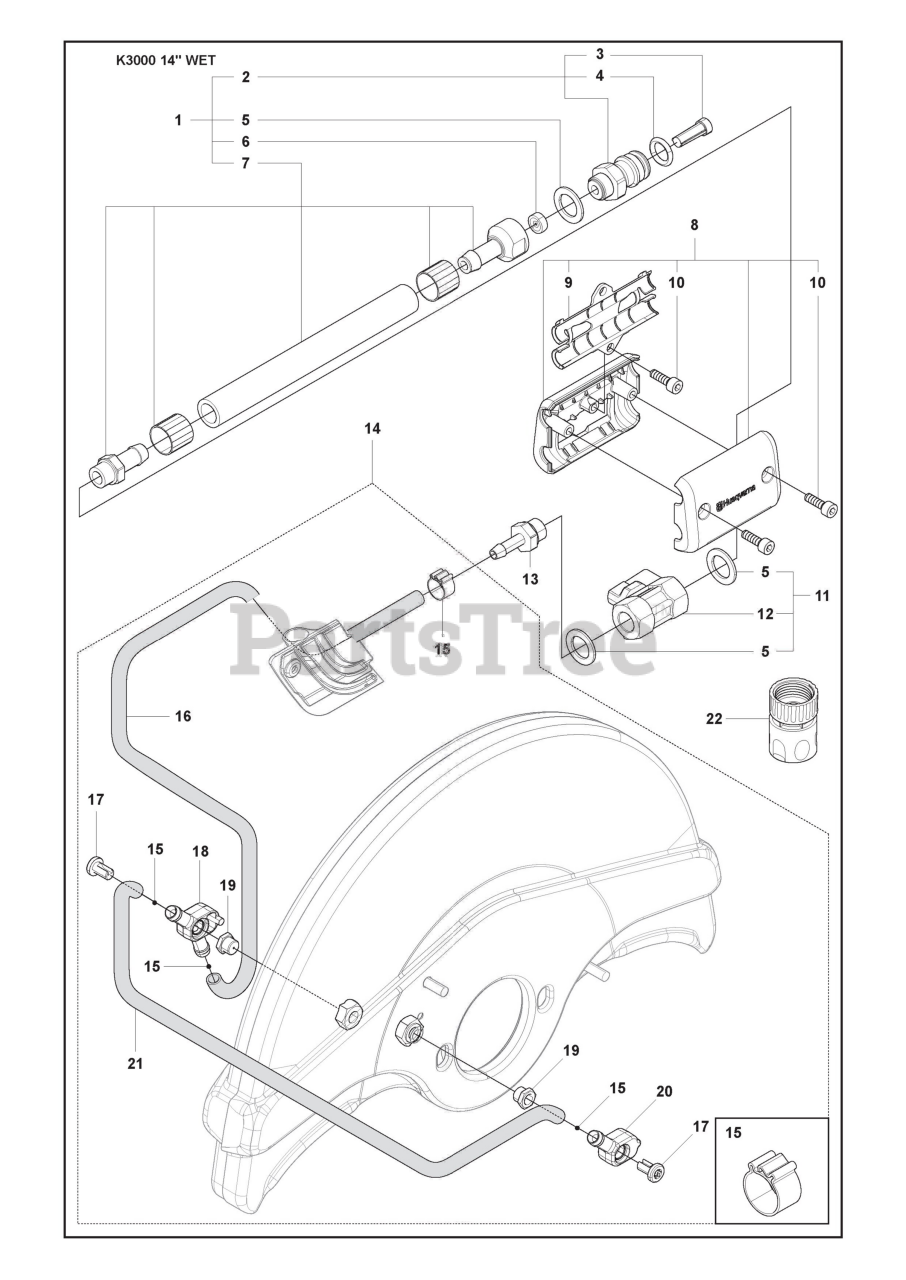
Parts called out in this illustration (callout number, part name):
1	Hose Assy
2	Nipple
5	Fibre Washer
6	Flow Control
7	Hose Assy
8	Valve Housing K3000 Wet
11	Valve Kit
14	Hose Kit
15	Hose Clamp
16	Hose
21	Hose
22	Coupler
